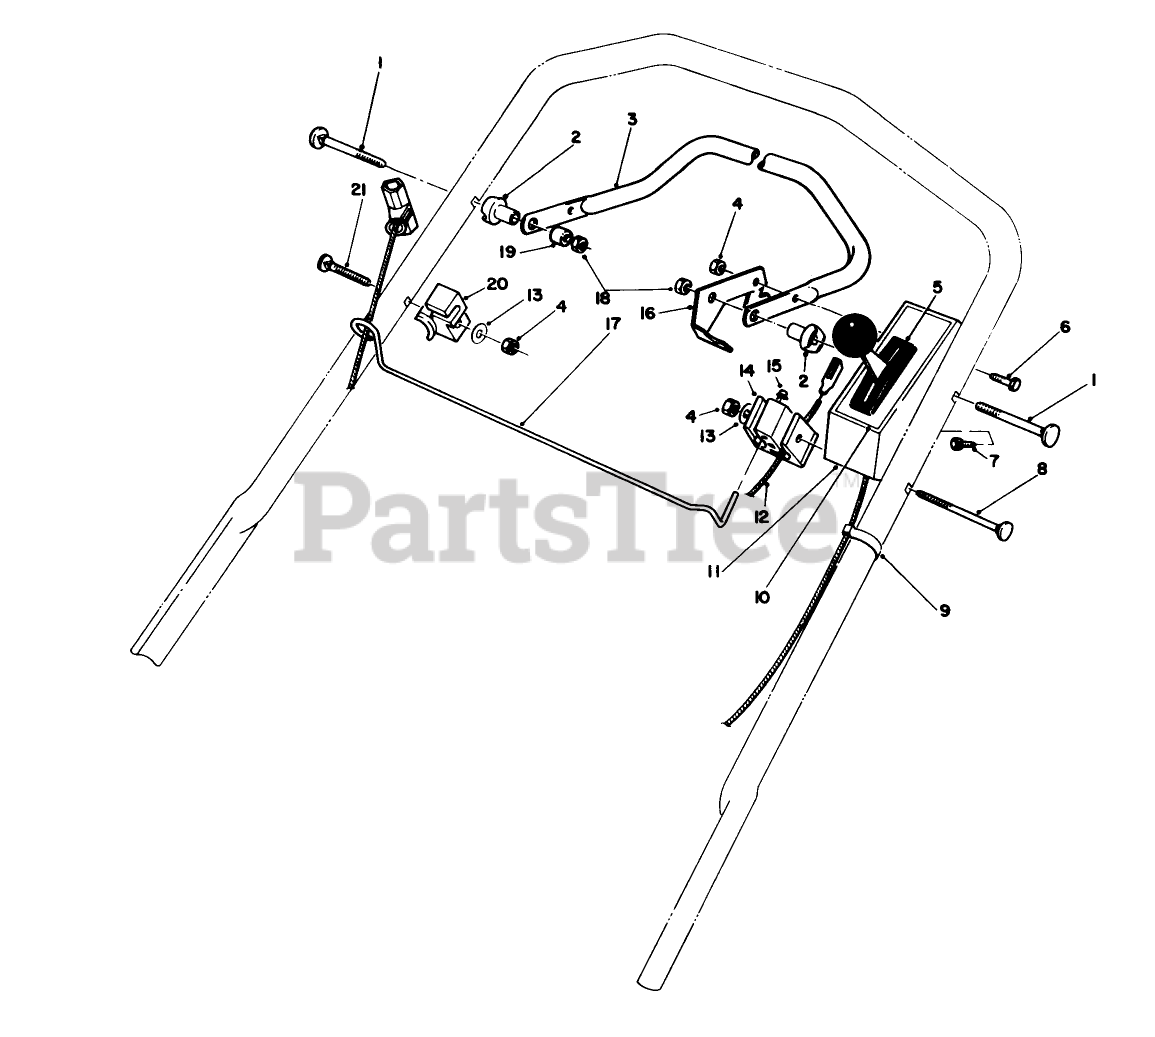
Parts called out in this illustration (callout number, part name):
1	5/16-18 X 2 HNDLE SCREW
2	SPACER-SUPPORT
3	Bar-Control
4	NUT-LOCK, NI
5	THROTTLE CONT-SERVICE
6	SCREW-HH
7	SCREW-HWHTF
8	HANDLE SCREW
9	BOWDEN CLIP
10	Decal-Control Cover
11	CONTROL COVER
12	BRAKE CABLE
13	WASHER-FLAT
14	SUPPORT-CABLE
15	NUT-SPEED
16	Lever-Control
17	ROPE ROD PLATED
18	NUT-LOCK, NI
19	SPACER-NYLON
20	ROD CATCH
21	SCREW-HANDLE
